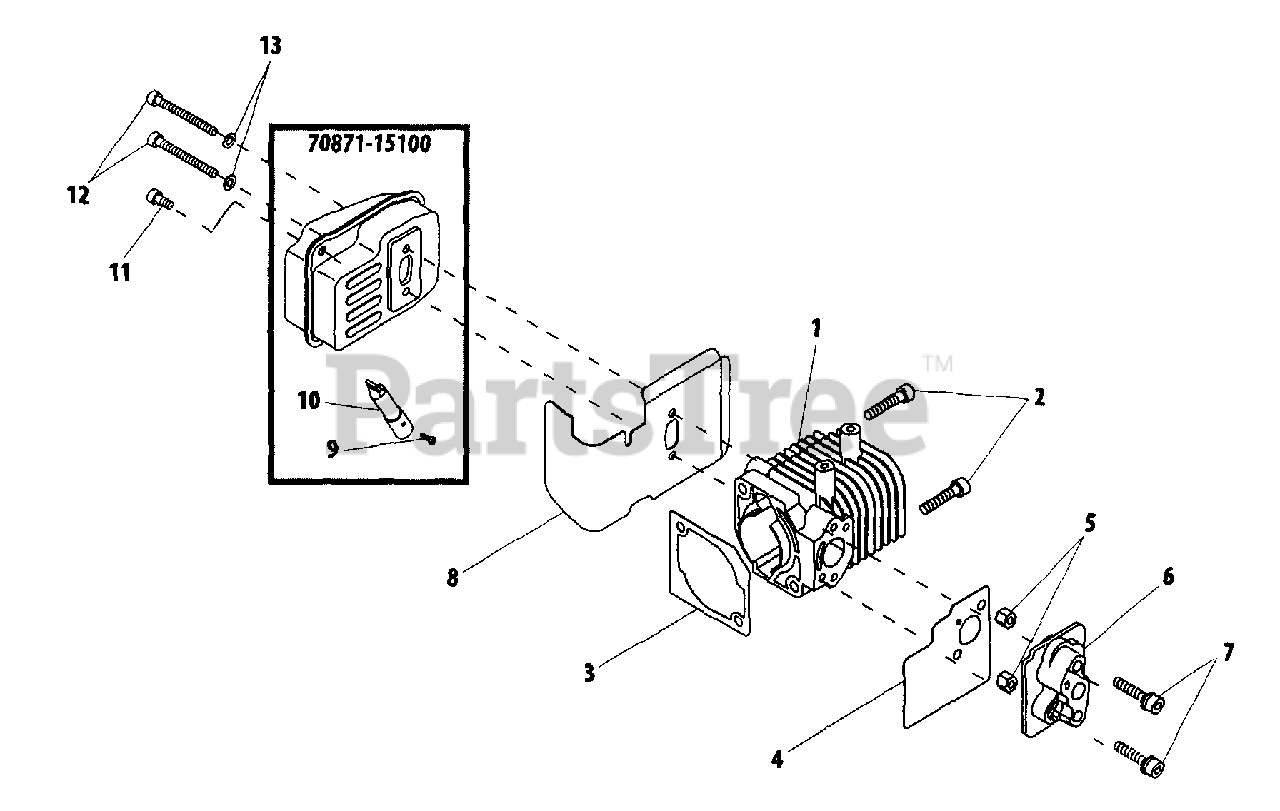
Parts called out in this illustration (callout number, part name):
1	CYLINDER
2	BOLT 5×25
3	GASKET, CYLINDER
4	GASKET
5	NUT M5×6.3
6	INSULATOR
7	BOLT M5×25
8	GASKET
9	SCREW, TAPPING 3×6
10	SCREEN, SPARK ARRESTER
11	BOLT 5×12
12	BOLT M5×50
13	WASHER, FLAT 5.5×10×0.8
70871-15100	MUFFLER ASSY
